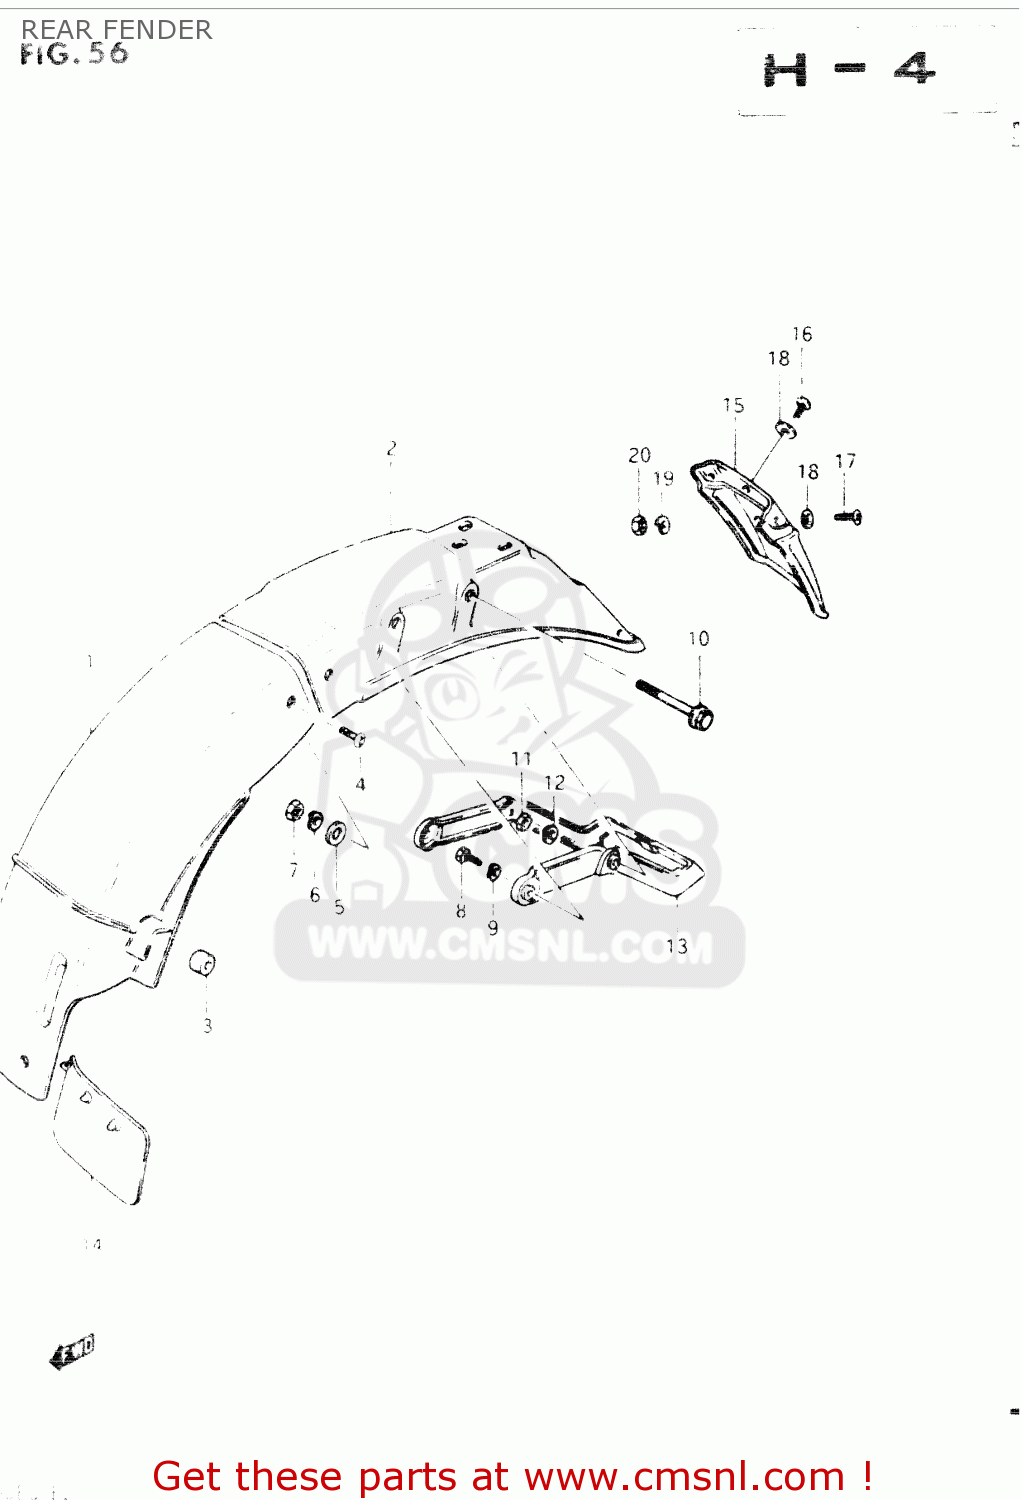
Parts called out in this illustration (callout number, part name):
1	FENDER,REAR
2	BODY,REAR FENDER,REAR
3	CUSHION
4	SCREW
5	WASHER (5.5X16X1.2)
6	LOCK WASHER
7	NUT
8	BOLT, UPPER
9	WASHER,LOCK
10	BOLT
11	NUT
12	LOCK WASHER
13	REINFORCEMENT,REAR FENDER
14	GUIDE,RR FENDER MUD
15	EXTENTION, REAR FENDER
16	SCREW 6X12
17	SCREW
18	WASHER(6.5X18X1)
19	WASHER,LOCK
20	NUT
